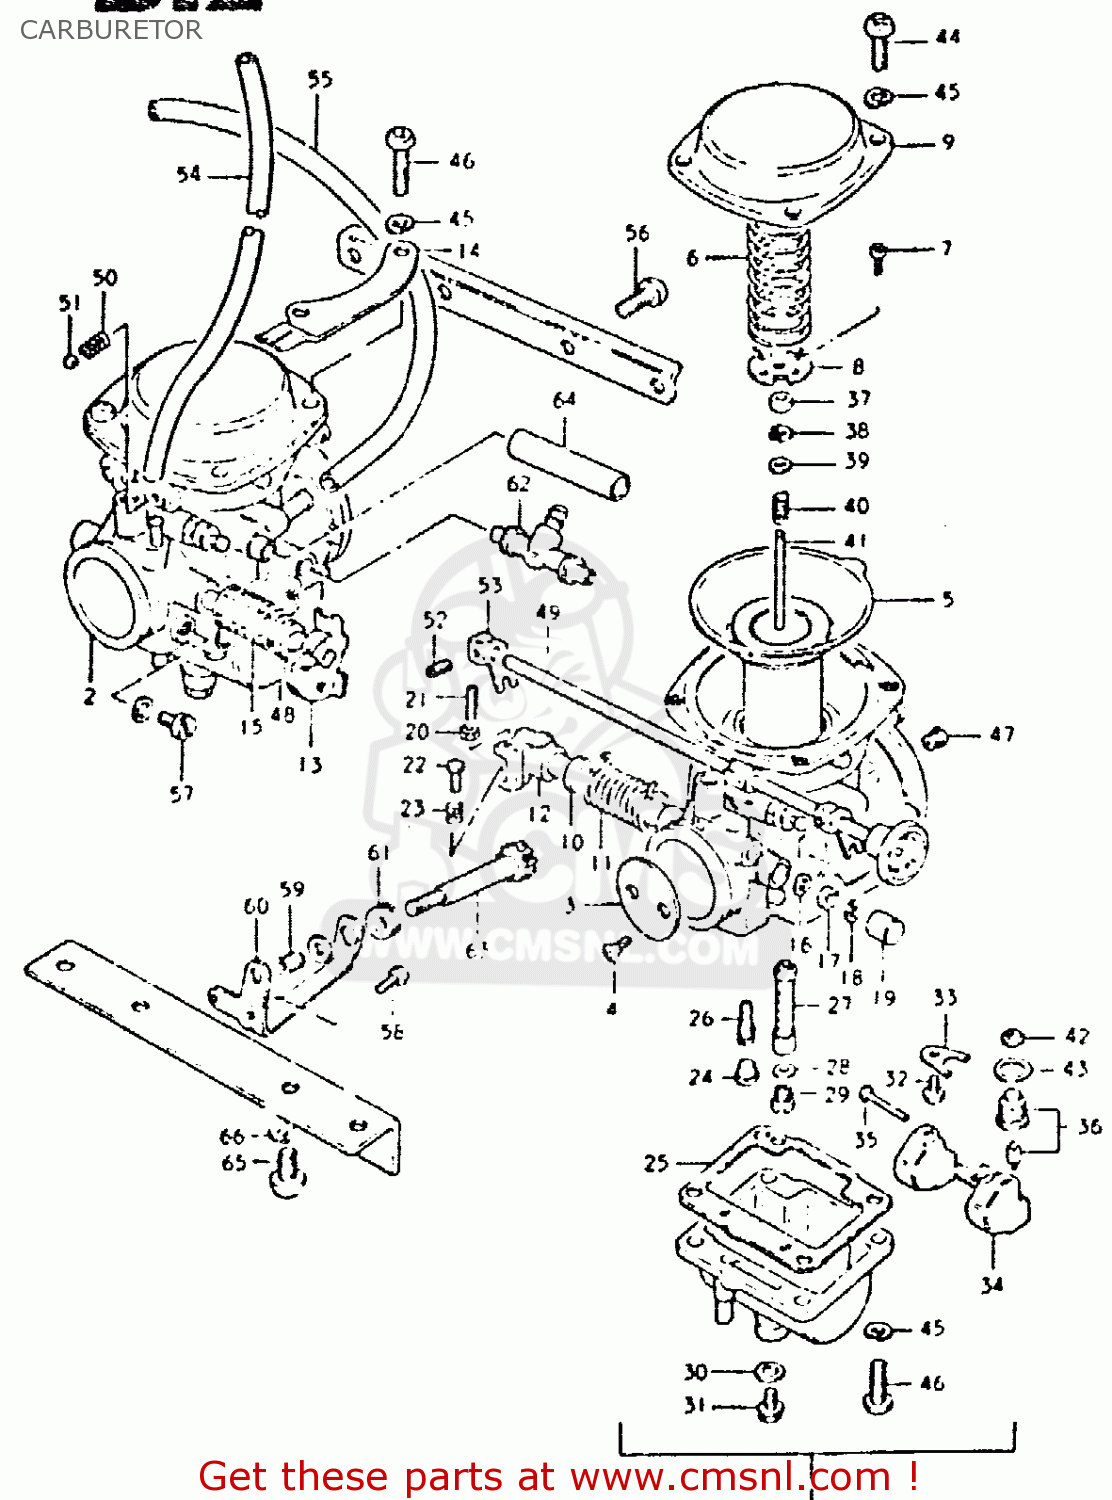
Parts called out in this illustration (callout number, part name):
1	CARBURETOR, LH
2	CARBURETOR, RH
3	VALVE, THROTTLE (135)
4	SCREW
5	DIAPHRAGM,CARBURETOR
6	SPRING
7	SCREW
8	PLATE
9	COVER,DIAPHRAGM
10	SPACER,THROTTLE SHAFT
11	SPRING
12	SHAFT ASSEMBLY
13	SHAFT,THROTTLE
14	BRACKET
15	SPRING
16	SEAL
17	GASKET,THROTTLE SHAFT (NAS)
18	E RING
19	CAP
20	NUT
21	SCREW
22	PIN,THROTTLE LEVER
23	SPRING,THROTTLE SCREW
24	PLUG,NEEDLE JET
25	GASKET,FLOAT CHAMBER (NAS)
26	JET, PILOT (42.5)
27	JET,NEEDLE(P-1)
28	WASHER,NEEDLE NOZZLE
29	JET
30	GASKET (NAS)
31	PLUG,DRAIN
32	SCREW 4X6
33	PLATE
34	FLOAT
35	PIN,FLOAT
36	VALVE ASSEMBLY,NEEDLE
37	RING
38	CLIP
39	PIN,FLOAT
40	SPRING
41	NEEDLE,JET
42	FILTER
43	O-RING,NEEDLE VALVE
44	SCREW
45	LOCK WASHER
46	SCREW
47	JET,AIR(125)
48	SPACER,THROTTLE SHAFT
49	SHAFT
50	SPRING
51	BALL,CARBURETOR
52	SCREW
53	LEVER
54	HOSE
55	HOSE
56	SCREW
57	SCREW
58	SCREW
59	SPRING,THROTTLE ADJUST
60	BRACKET,THROTTLE ADJUST
61	CAP
62	NIPPLE,CARBURETOR
63	SCREW
64	HOSE
65	SCREW 6X12
66	LOCK WASHER
